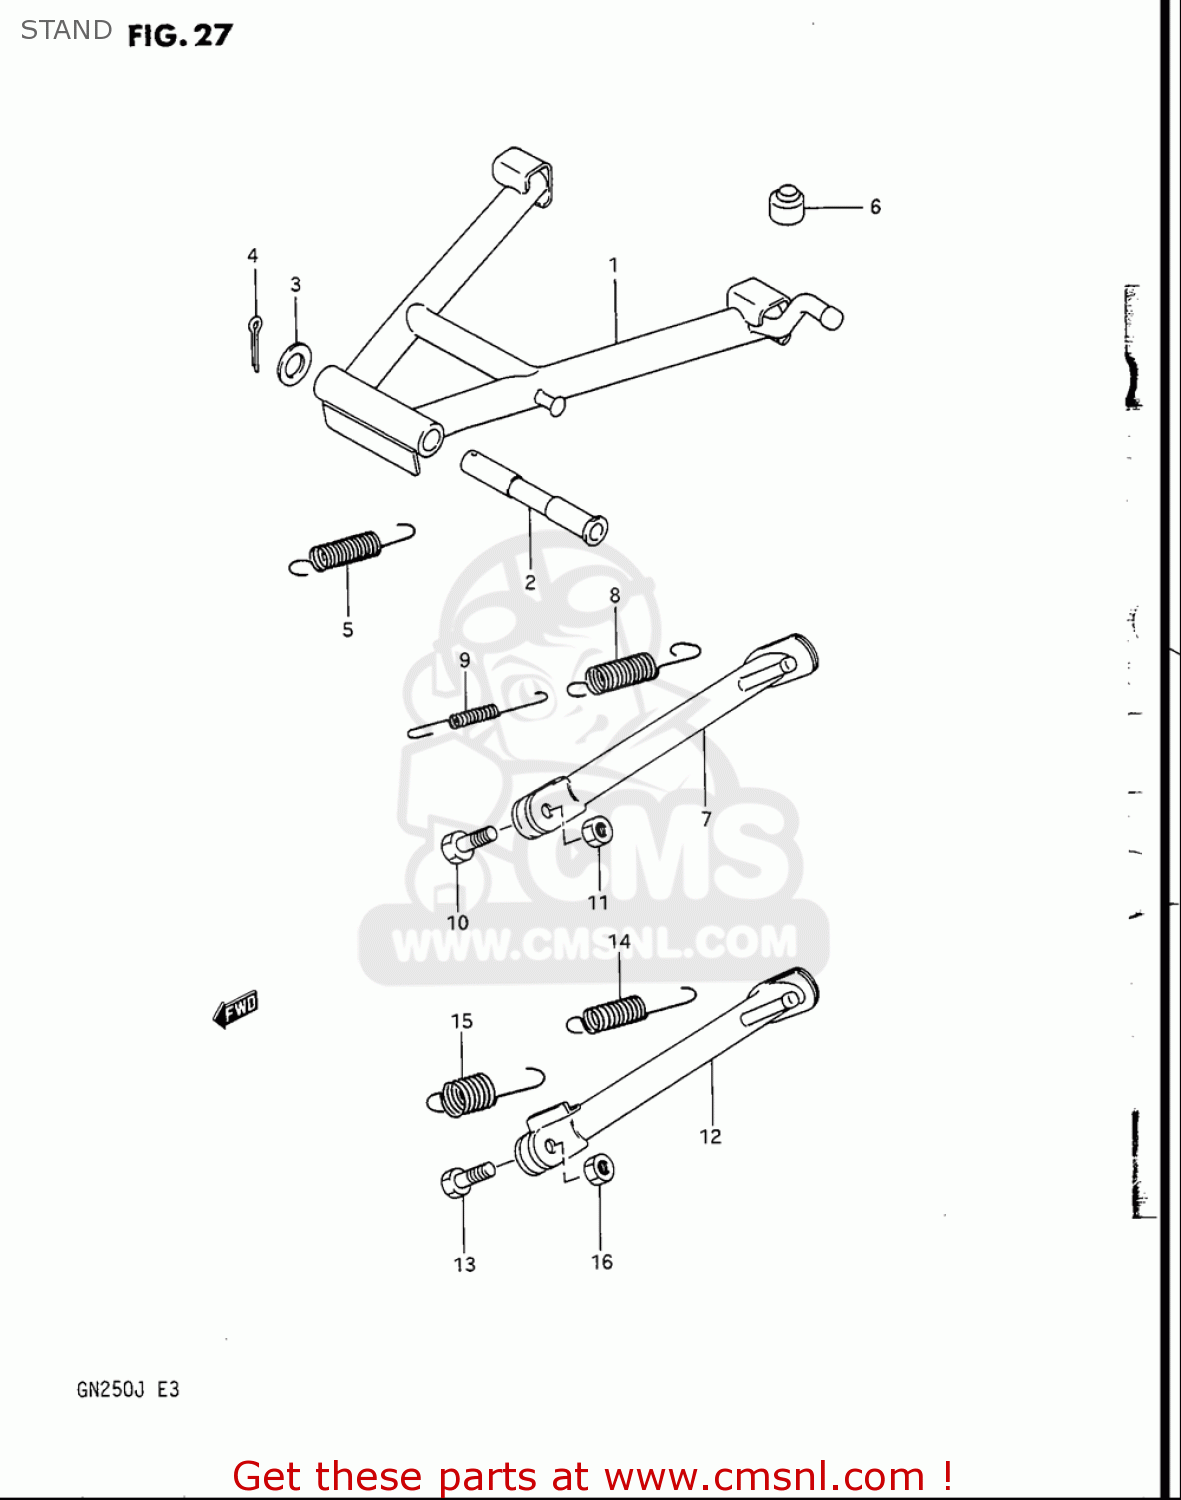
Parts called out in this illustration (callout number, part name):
1	STAND,CTR
2	SHAFT UH125
4	PIN
5	SPRING
6	CUSHION
7	STAND,SIDE
9	SPRING
10	BOLT(10X30)
11	NUT
12	STAND,PROP
13	BOLT(10X30)
14	SPRING
15	SPRING
16	NUT
